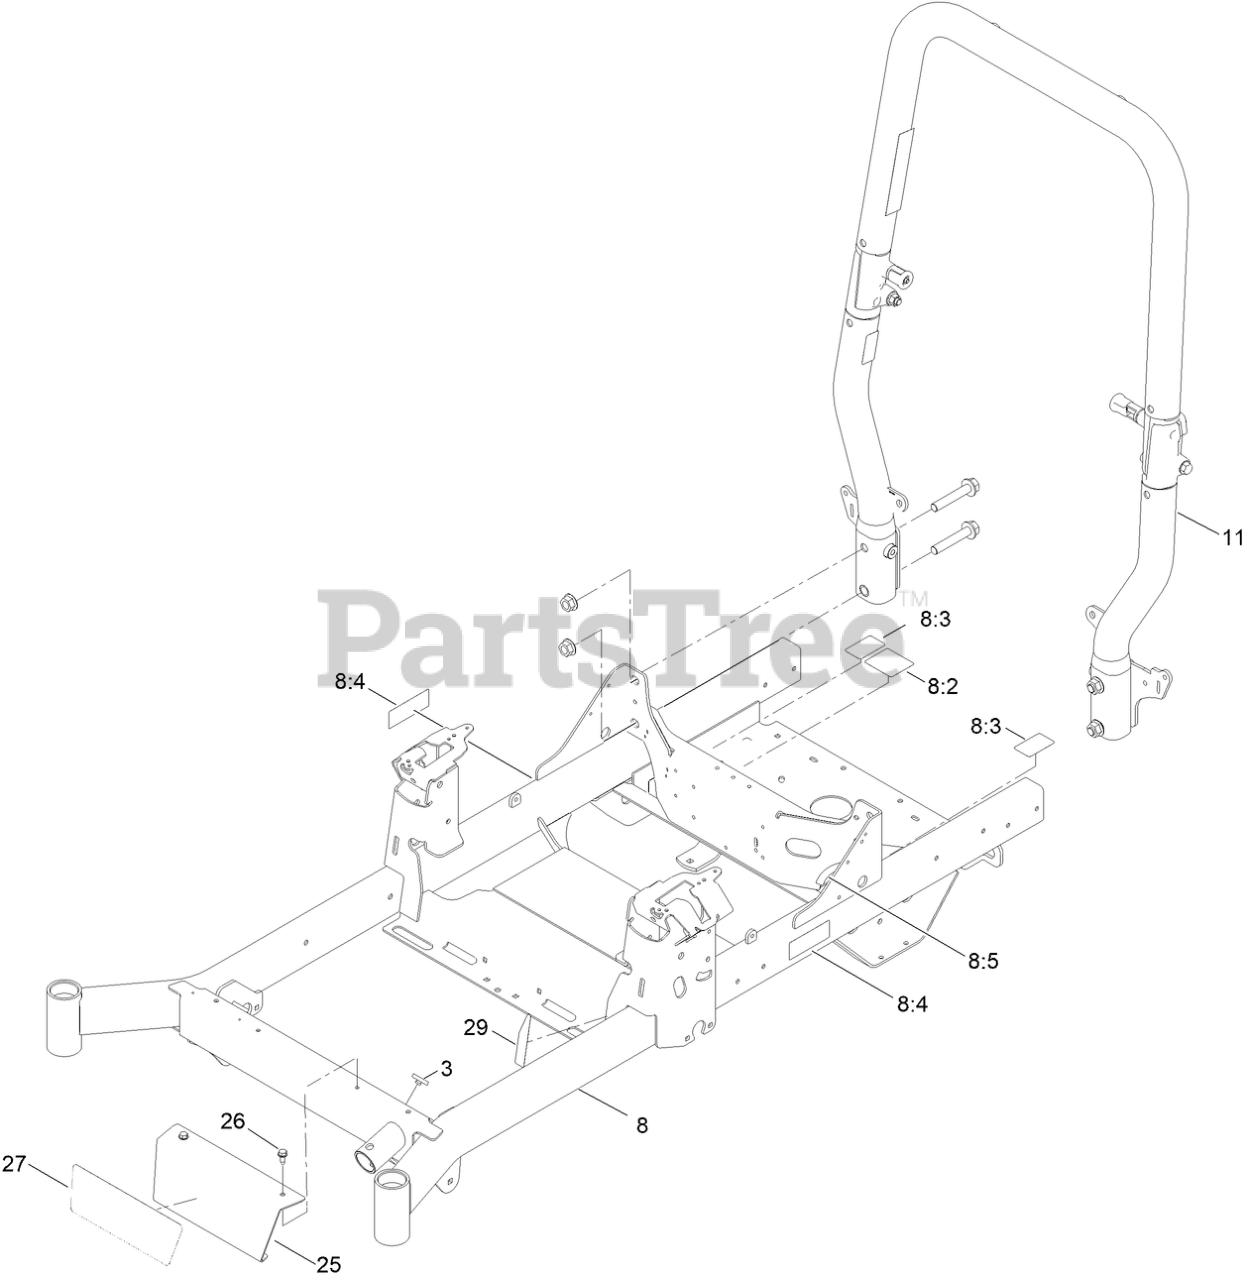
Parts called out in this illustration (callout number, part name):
3	BUMPER-PUSH-IN, RUBBER
8	SUSPENSION FRAME ASM
8:2	DECAL-ROUTING, BELT
8:3	DECAL-RELEASE, DRIVE
8:4	DECAL-WARNING
8:5	STRIP-SEAL
11	ROPS ASM
25	PLATE-FRONT
26	SCREW-HWHTF
27	DECAL-Z MASTER
29	DECAL-FILL, FUEL
